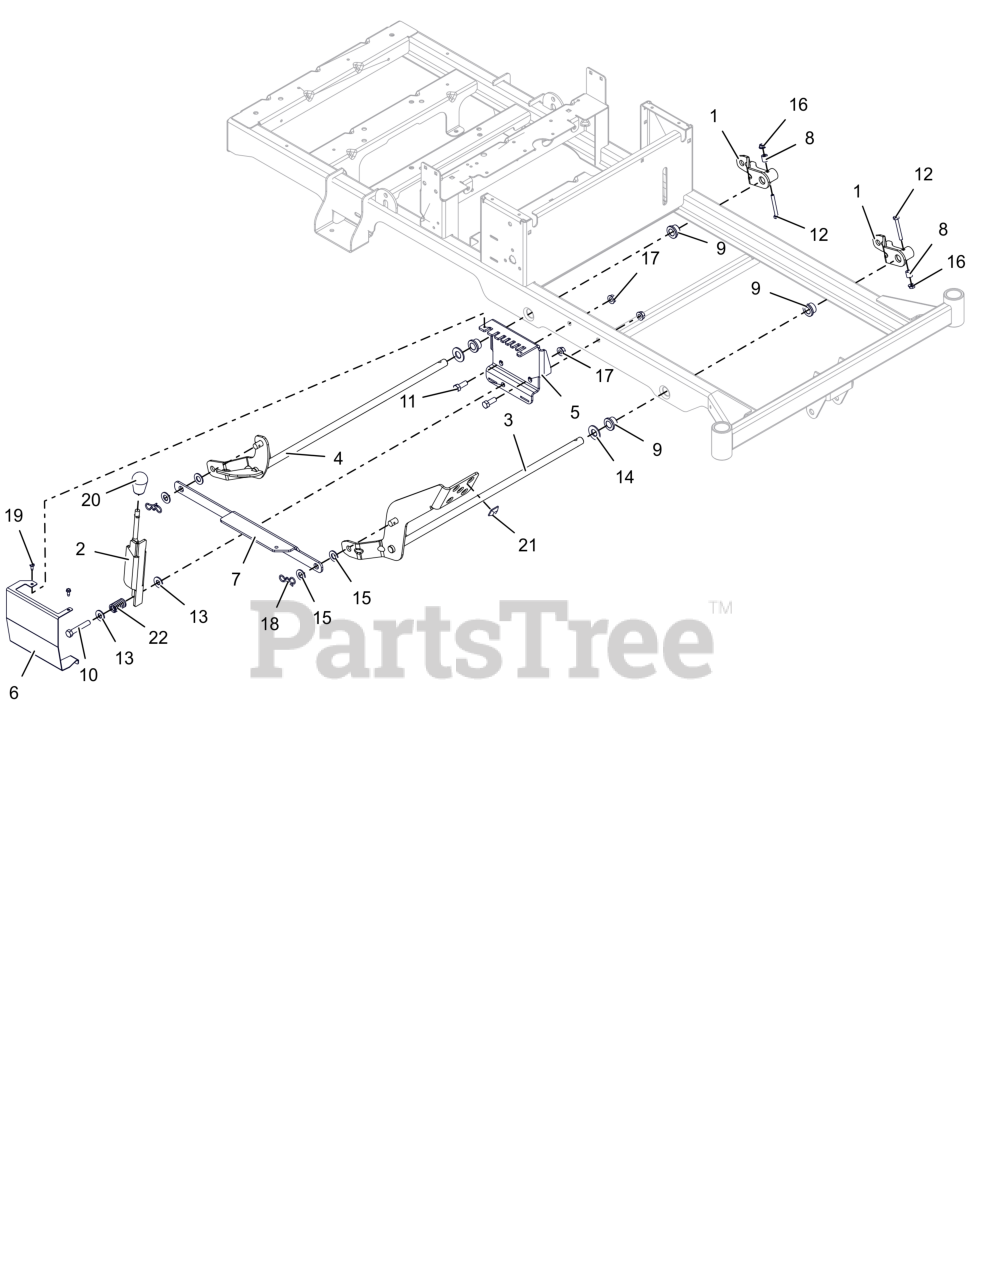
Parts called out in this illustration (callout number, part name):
1	WLDMT, DECK LIFT ARM (RED)
2	WLDMT, HEIGHT OF CUT (RED)
3	WLDMT, PEDAL DECK LIFT (RED)
4	WLDMT, REAR DECK LIFT (RED)
5	PLATE, HEIGHT ADJUSTMENT (RED)
6	GUARD, DECK HOC (RED)
7	LINK, LIFT /HOC (RED)
8	BSHG-SLV .265X.500X.500
9	BSHG-FLG .629X.879X.469X1.250
10	BLT,HEX .38-16X2.25 G5 ZCC
11	BLT,HEX .38-16X1.00 G5 ZCC
12	BLT, HEX .25-20X2.00 G5 ZCC
13	WSHR,FLT .438X1.00X.083 ZCC
14	WSHR, FLT .656X1.313X.095 ZCC
15	WSHR-FL-NYL .518X1.000X.080
16	NUT-LK-CTR-FLG .25-20 ZC120
17	NUT-LK-CTR-FLG .375-16 GF ZCC
18	PIN, BOWTIE .091X1.875 ZCC
19	SCR,TAP #10-24X.50 HWH TR ZCC
20	KNOB,SOFT TEARDROP,PUSH-ON BLK
22	SPRG, COMPRESSION
